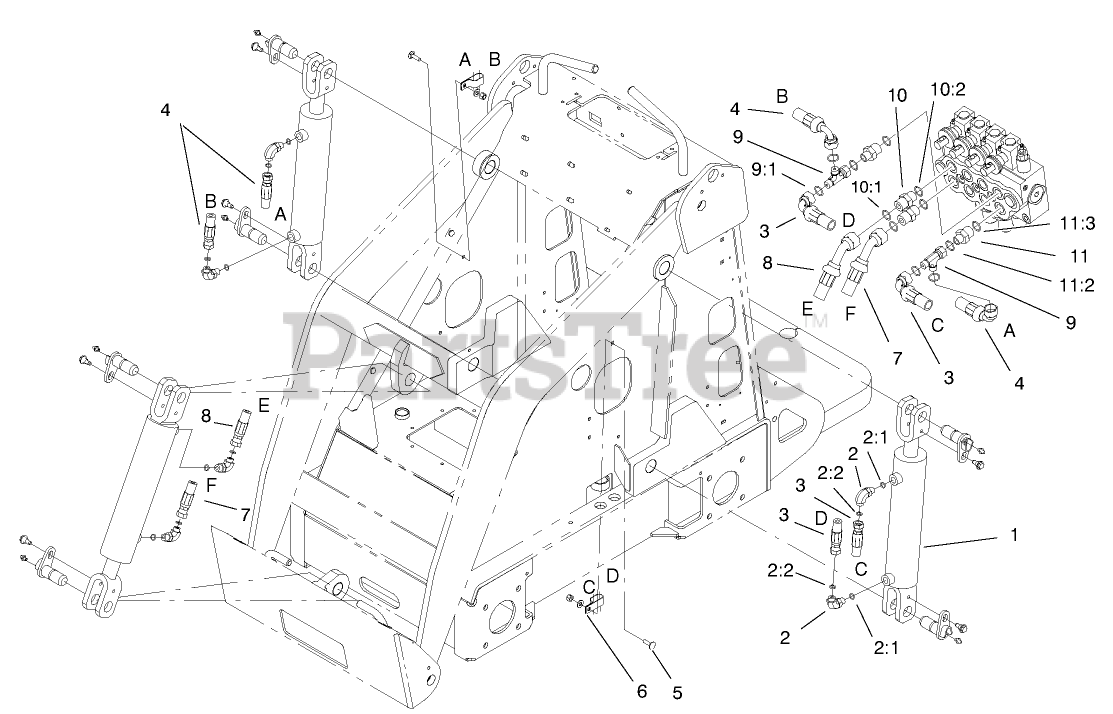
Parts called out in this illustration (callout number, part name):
1	Cylinder-Hydraulic (Serial # Range 990001-990999)
1	Cylinder-Hydraulic
2	FITTING-ELBOW 90
2:1	O-RING
2:2	O-Ring
3	HYD HOSE ASM
4	HOSE-HYD
5	BOLT-CARR
6	CLAMP-R, DOUBLE
7	HOSE-HYD
8	HOSE-HYD
9	FITTING-HYD
9:1	O-Ring
10	FITTING-STRAIGHT
10:1	O-RING
10:2	O-RING
11	FITTING-STR
11:2	O-RING
11:3	O-Ring
